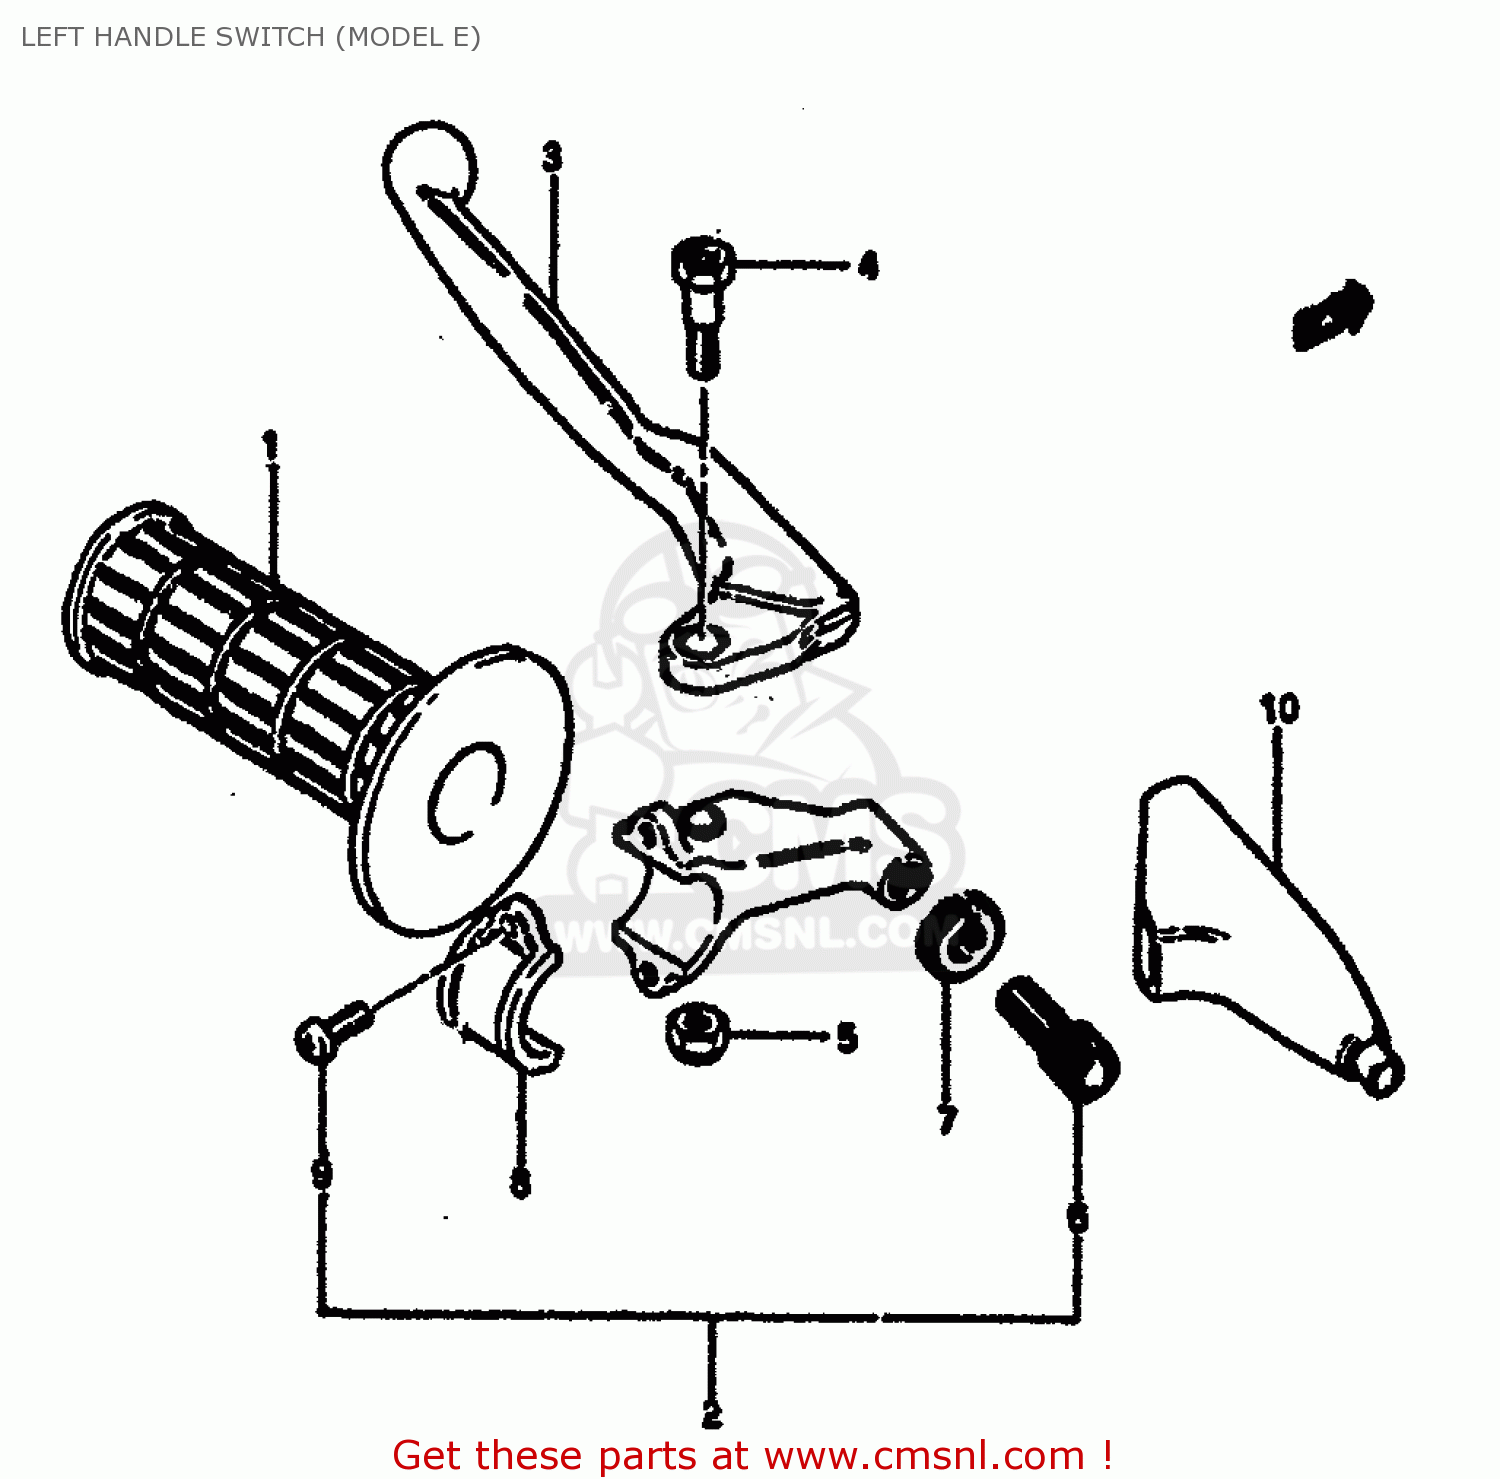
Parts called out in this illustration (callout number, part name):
1	GRIP,LEFT
2	LEVER ASSY,CLUTCH
3	LEVER,CLUTCH
4	BOLT,LEVER
5	NUT 6MM
6	ADJUSTER,CABLE
7	NUT,CABLE ADJUSTER
8	BRACKET,CLUTCH LEVER HOLDER
9	SCREW
10	COVER,CLUTCH LEVER
